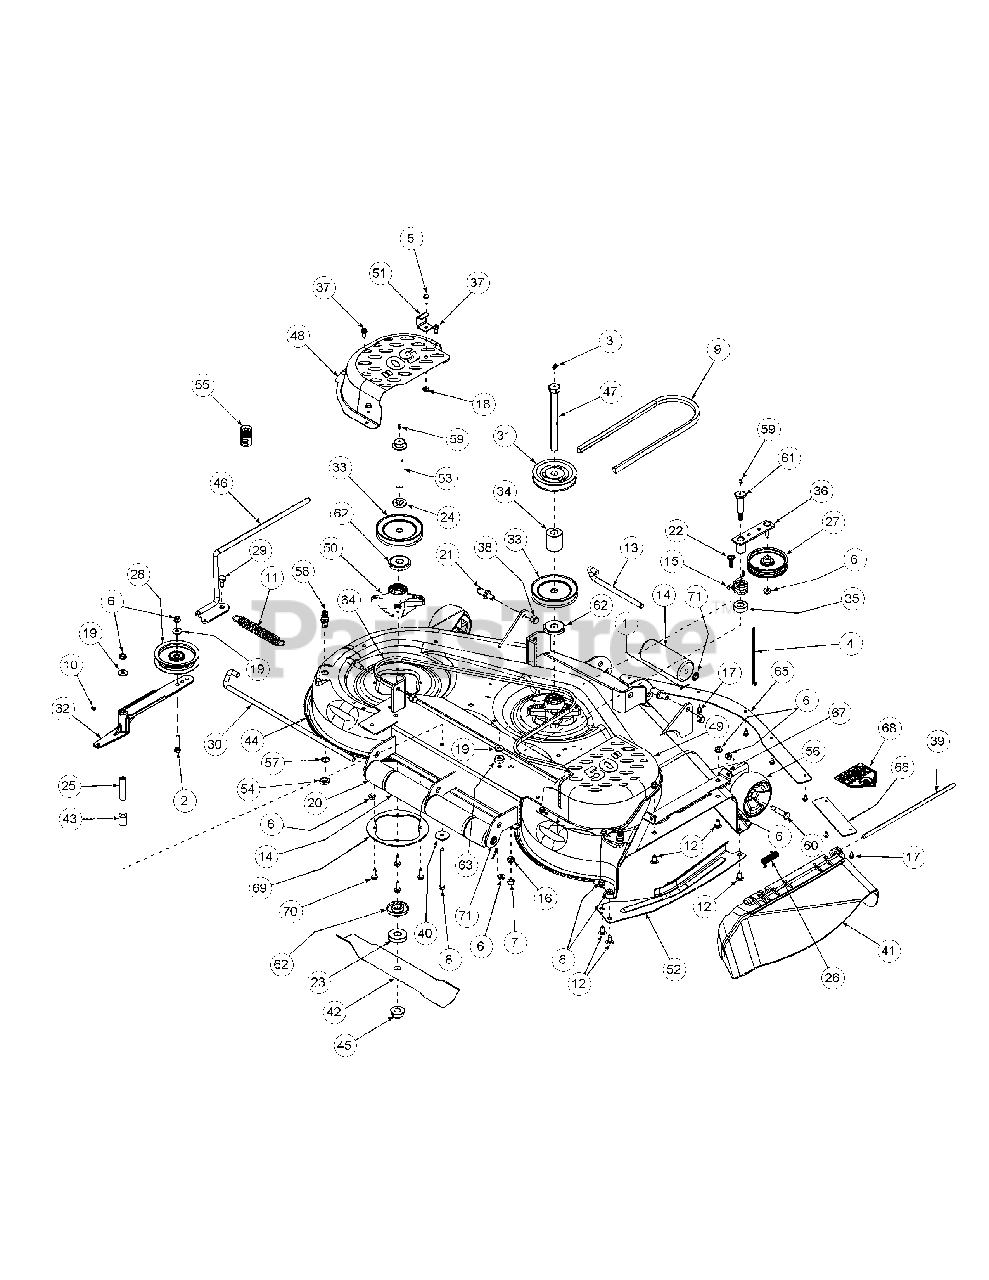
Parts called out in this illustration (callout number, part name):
1	Cotter Pin, .125 Dia x 1.0
2	Capscrew, 3/8-16 x 1-3/4
3	Grease Fitting, 1/4-28, 90?
4	Cable Tie, 3/16 x .05 x 7.4
5	Hex Cap Screw, 5/16-18 x 3/4
6	Hex Nut Flange lock, 3/8-16
7	Nut 7/16-14, Nylock
8	Hex Cap Screw, 3/8-16 x 5.00
9	V-Belt, B-Section
10	Grease Fitting, 1/4-28 x 3/16
11	Extension Spring, 1.0 OD x 5.00
12	Carriage Bolt, 3/8-16 x .75 Lg
13	Roller Pin, 1/2 Dia x 7.31 Lg
14	Front and Rear Roller
15	Torsion Idler Spring
16	Flat Washer, .469 ID x .875 OD x .105
17	Screw, TT, 1/4-20 x .5, Hex Index Washer
18	Hex Flange Lock Nut, 5/16-18
19	Flat Washer, .406 ID x 1.0 OD x .105
20	Short Roller
21	Pin, 5/8 Dia x 1.2 Lg
22	Carraige Screw, 3/8-16 x 1.25
23	Spacer, .76 ID x 2.00 OD x .477
24	Spacer, .812 ID x .218 Lg.
25	Spacer, .39 ID x .625 OD x 2.75
26	Torsion Spring
27	Flat Pulley with Flanges
28	Idler Pulley, 4.06 OD with Deep Flange
29	Shoulder Screw, .50 x .27 Lg; 3/8-16
30	Roller Pin Rod
31	V-Pulley, 4.75 OD
32	Idler Arm Assembly, Flat Top Bearing
33	Pulley, A Sect x 4.90
34	Spacer, .760 ID x 1.75 OD x 1.969
35	Spacer .760 ID x 1.5 OD
36	Idler Arm Assembly
37	Self Tapping Screw 5/16-18 x .750
38	Hex Nut, 1/2-13, Insert Lock
39	Hinge Pin, .375 x 14.06
40	Flat Washer, .390 x 1.5 x .134
41	Chute Deflector
42	Hi-Lift Blade, 17.9
43	Spacer, .39 ID x .875 OD x 1.00
44	Deck Assembly 50"
45	Flange Hex Nut, 3/4-16
46	Spring Tension Rod Assembly
47	Hex Cap Screw, 3/4-16 x 8.00
48	Left Hand Belt Cover
49	Right Hand Belt Cover
50	Blade Spindle Assembly
50	Cup, Bearing
50	Bearing, Cone
50	Spacer, Bearing
50	Seal, Oil, 1.25 x 1.874 x .25
51	Tension Rod Stop Bracket
52	Finger Guard
53	Spindle Bolt 3/4-16 x 5.37
54	Hex Nut, M16-1.5
55	Adaptor, Water Nozzle
56	Deck Wheel, 5.00 Dia.
57	Lock Washer, 17 x 23.8 x 1.9
58	Nozzle, Deck Water
59	Grease Fitting
60	Shoulder Screw .498 x 1.53
61	Shoulder Screw .68 x 2.11
62	Spindle Spacer
63	Spacer .406 ID x 1.00 OD x 0.38
64	V-Belt, 1/2 x 91 LG
65	Skirt, Center, 50"
66	Skirt, Right Hand, 50"
67	Chute Mounting Bracket
68	Decal, Danger Hands & Feet
69	Spindle Plate
70	Self Tapping Screw 5/16-18 x 1.00
71	Push Nut,.480 ID X 1.00 OD
